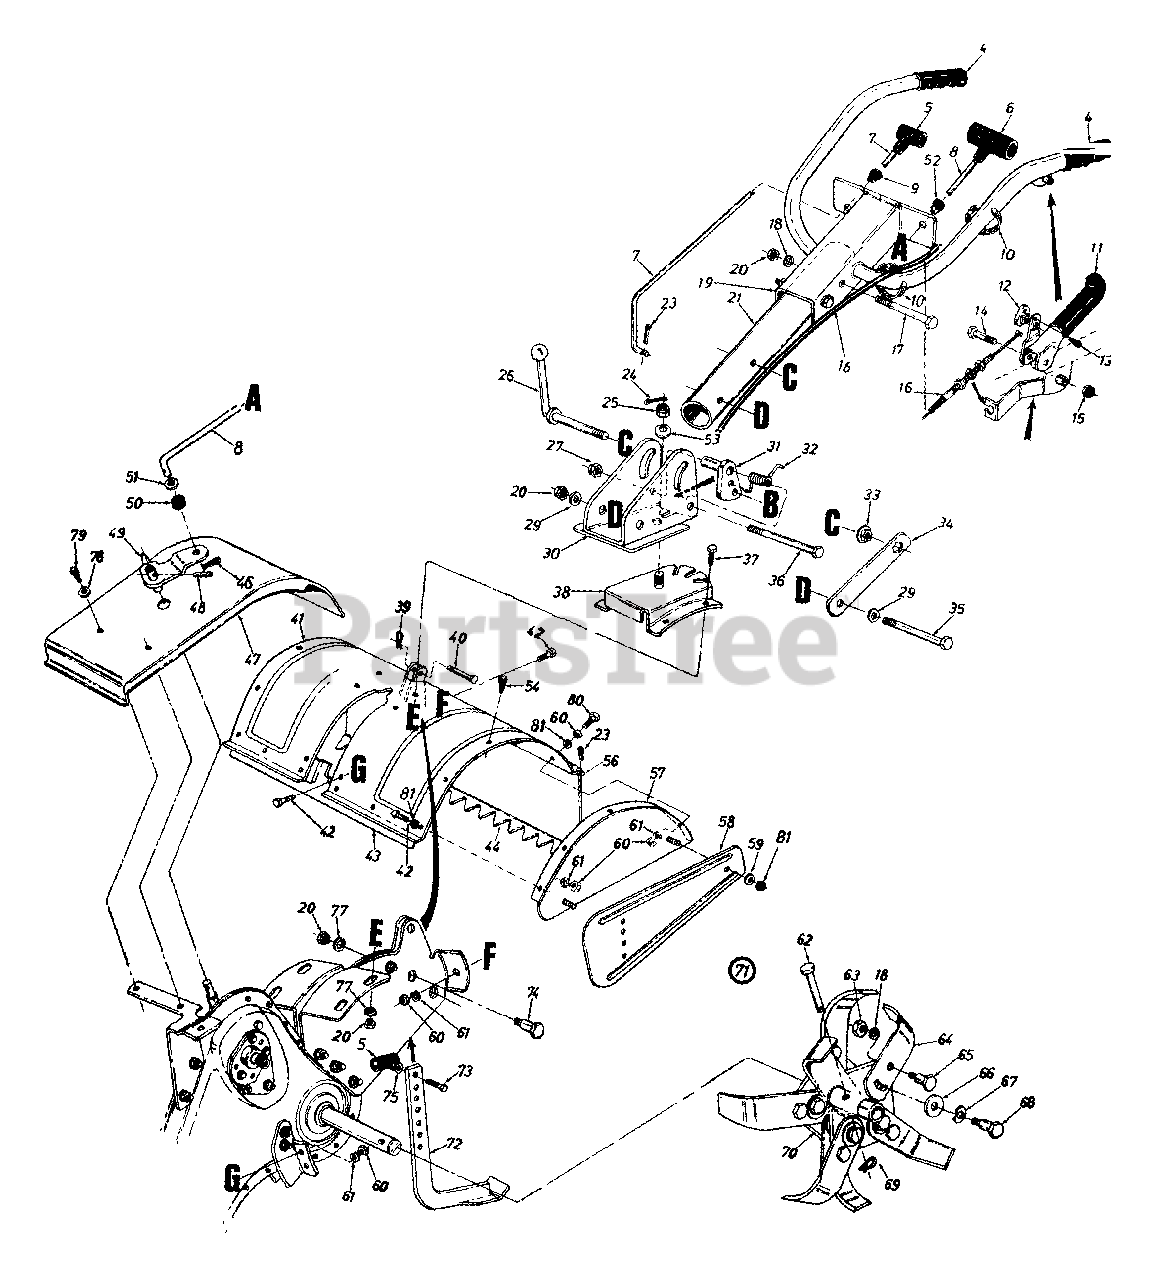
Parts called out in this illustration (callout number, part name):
4	Handle Grip
5	Small "T" Knob
6	Large "T" Knob
7	Clutch Rod
8	Control Rod 37" Lg.
9	Snap On Bushing 3/8" Dia.
10	Cable Tie-Self Clinching
12	Barrel Cable Hold Down
13	Hex B-Tap Scr. #10 x .44" Lg.
14	Hex Bolt 3/8-24 x 2.25" Lg.
15	Hex Jam L-Nut 3/8-24 Thd.
16	Clutch Control Cable 46" Lg.
17	Hex Bolt 3/8-16 x 3.00" Lg.
18	L-Wash. 3/8" I.D. - H.D.
24	Cotter Pin 3/32" Dia. x 1.25" Lg.
25	Hex Slotted Nut 5/8-18 Thd.
26	Handle Adj. Crank
27	Hex Cent. L-Nut 3/8-16 Thd.
29	Bell-Wash. .4" I.D. x .87" O.D.
32	Spring Handle Adj. (Torsion)
33	Hex Flange Nut 3/8-24 Thd.
34	Bracket Hex Nut Retainer
35	Hex Bolt 3/8-16 x 3.25" Lg.
36	Hex Bolt 3/8-16 x 3.00" Lg. - Gr. 8
37	Hex Bolt 3/8-16 x 1" Lg
40	Clevis Pin .375" Dia.
43	Bracket Reinforcement - 18"
46	Intern. Cotter Pin 5/16" Dia
49	Shifting Crank Ass'y
50	Rubber Washer 33" i.D
51	Fl-Wash 4" I.D x 1.25" O.D.
52	Snap On Bushing 1/2" Dia.
53	Bell-Wash. .63" I.D. x 1.25"
54	Hex Wash Tap Scr
56	Tiller Flap Rod
60	Hex Nut 5/16-18 Thd.
61	L-Wash 5/16" I.D.
62	Clevis Pin .375" Dia
63	Hex Nut 3/8-24 Thd.
65	Shld. Bolt 1/2" Dia. x .175
66	FI-Wash. .51" I.D. x 1.50"
67	Bell-Wash 515" I.D. x 1.14"
68	Shld Bolt 1/2" Dia. x .320
69	Intern. Cotter Pin
73	Hex Bolt 3/8-16 x .75" Lg.
74	Shld. Bolt 1/2" I.D. x .62" Lg
75	Fl-Wash. 3/8" I.D. x 5/8" O.D
77	L-Wash 3/8" I.D.
78	Fl-Wash .281" I.D x .62"
79	Hex Wash. Self-Tap Scr 1/4-20 x 50" Lg.
80	Hex Bolt 5/16-18 x 11/4" Lg.
81	Cap L-Nut 5/16-18 Thd
